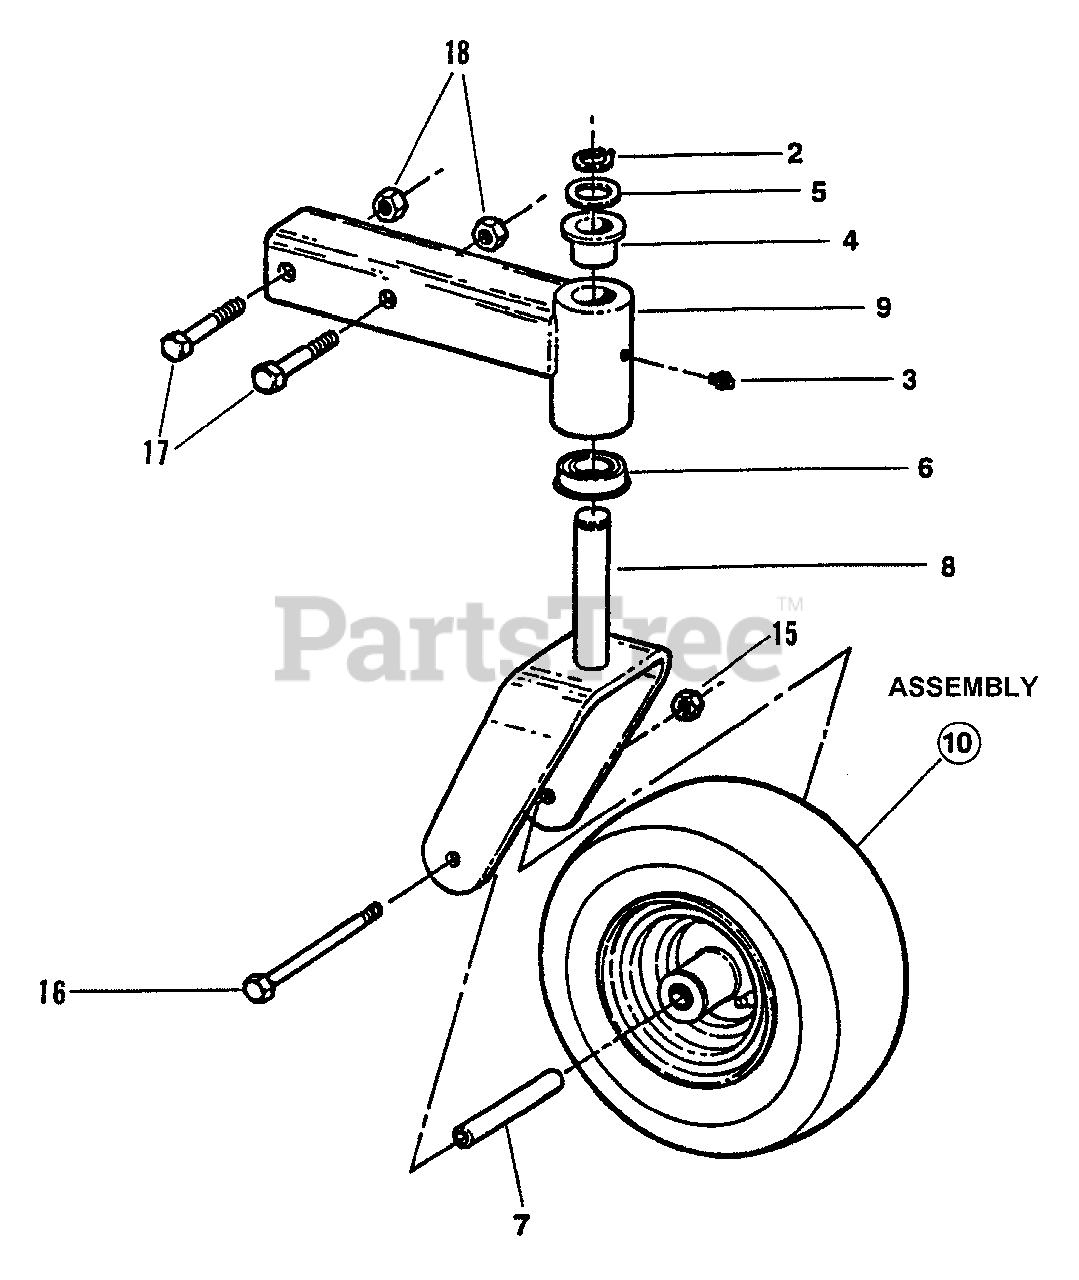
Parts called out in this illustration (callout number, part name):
2	RING, 1" External Retaining
3	LUBE FITTING, Straight (press-fit for .187 dia. Hole)
4	BUSHING, Caster
5	BUSHING, 1" Machine
6	BEARING, Flanged Ball
7	TUBE, 5/8" x 18 Ga. Wall x 3.545
8	YOKE, Caster (Weldment)
9	ARM, Telescoping Caster (Weldment)
10	ASSEMBLY, Wheel
15	NUT, 7/16-14 HEX NYLON LOCK
16	SCREW, 7/16-14 x 6" Hex Head Cap, Grade 5
17	BOLT, 1/2-13 X 3" GD5 CZ
18	NUT, 1/2-13 HEX NYLON LOCK
